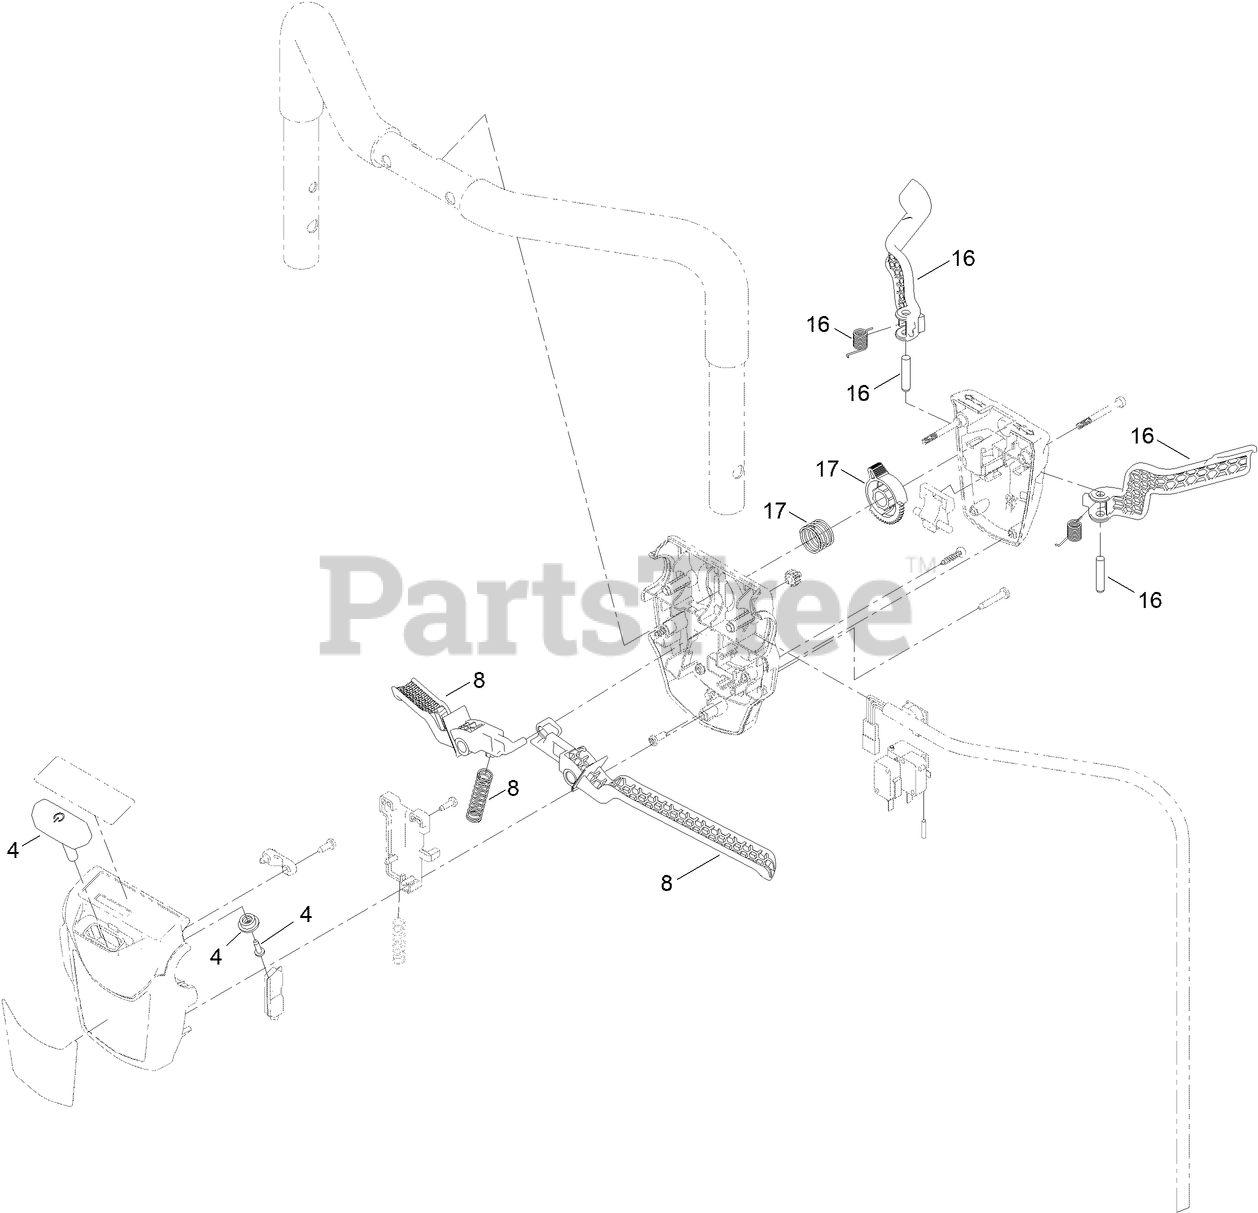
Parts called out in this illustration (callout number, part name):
4	TOP BUTTON KIT
8	UPPER LEVER KIT (43)
16	LOWER LEVER KIT
17	SPEED CONTROLLER WHEEL KIT
